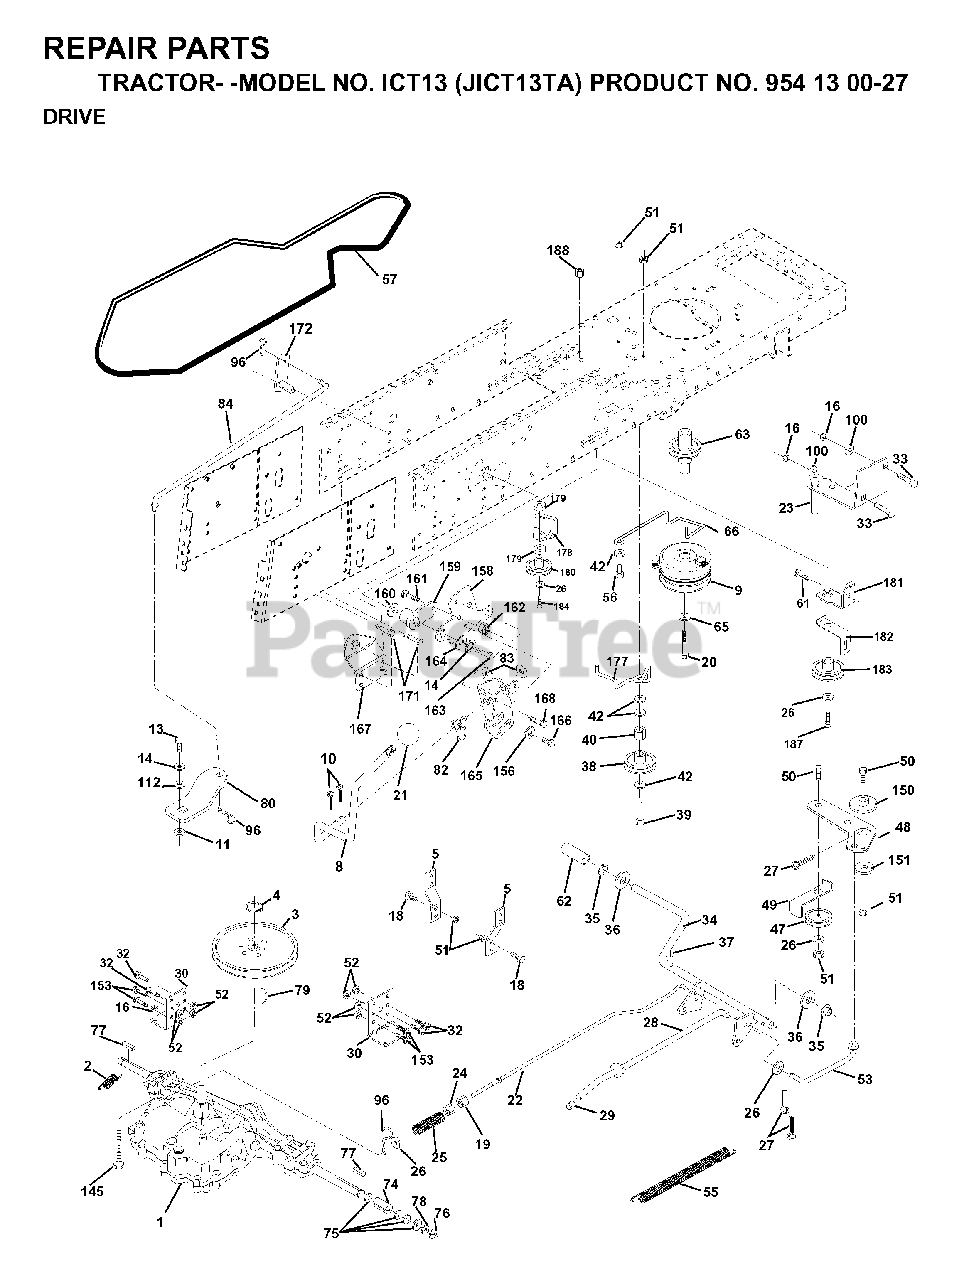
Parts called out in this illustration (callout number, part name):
2	SPRING,BRAKE RETURN
4	RETAINING RING LT
5	STRAP TORQUE
8	ROD SHIFT
9	CLUTCH
10	PIN COTTER
11	WASH-SHFT PLT LT
13	BOLT 1/4-28X3/4
14	LOCKWASHER
16	NUT.71038.31-18.HEX.NYLOCK
19	NUT
20	BOLT HEX
21	KNOB T (1/2-HOLE)
23	BRACKET, ASM CLUTCH MTG
24	NUT
25	SPRING ROD LT
27	COTTER PIN
28	ROD BRAKE PARK LT
29	CAP
30	BRACKET TRANSAXLE
32	BOLT
33	BOLT
35	BEARING.NYLON
36	WASHER LT
37	DRIVE PIN
38	PULLEY.FLAT
42	WASHER
47	IDLER PULLEY
48	BELLCRANK, CLUTCH
49	RETAIN BELT
50	BOLT
51	LOCKNUT
52	LOCKNUT
53	LINK, CLUTCH LT
55	SPRING, RETURN LT
57	V-BELT.KEV.111"
61	SCREW
62	PEDAL COVER T
63	PULLEY, CLUTCH ELECT EVX
65	LOCKWASHER
66	KEEPER BELT ENGINE
74	SPACER AXLE
76	E-RING LT
77	SQUARE KEY
80	ARM SHIFT
82	SPRING,TORSION
83	WASHER
96	RETAINER M
100	WASHER M
112	WASHER LT
150	BUSHING.BELLCRANK.GRD.DR
151	WASHER 12/32X2X10GA
153	BOLT RB
156	WASHER.SRRTD.5/16
158	BRACKET
159	HUB
161	BOLT
162	NUT.CROWNLOCK.1/4
165	RP BRACKET
167	BRACKET
168	BOLT.SHOULDER.5/16-18X
180	PULLEY.FLAT.IDLER
182	KEEPER BELT
183	PULLEY.V-IDLER
184	SCREW.HXWSH.3/8
187	SCREW
188	SNAP BUSHING T
